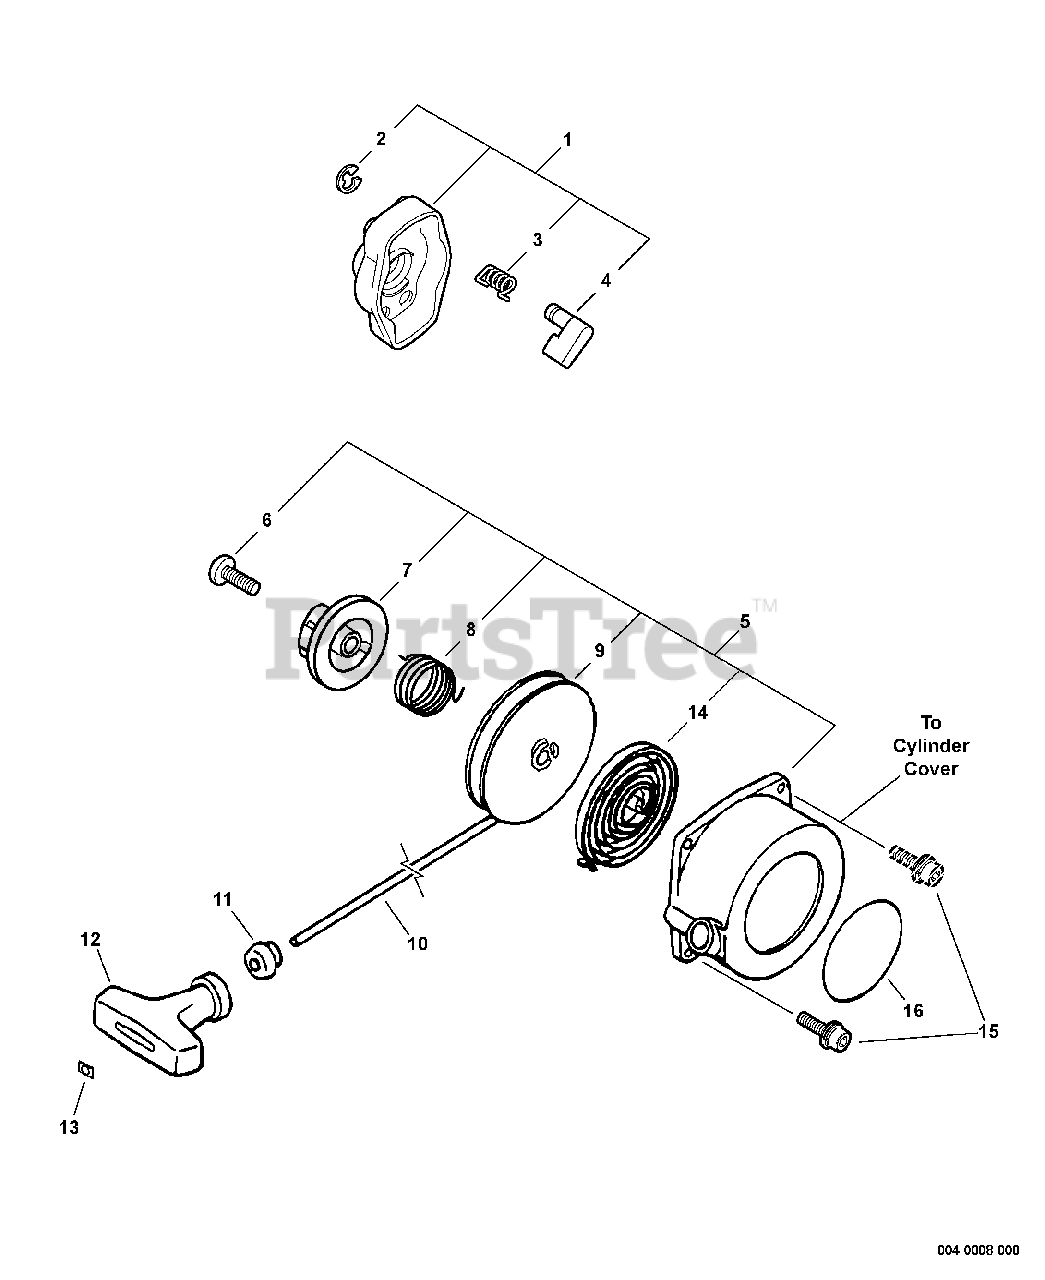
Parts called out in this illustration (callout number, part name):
1	PAWL ASSY, STARTER
2	E-RING 4
3	SPRING, RETURN
4	PAWL, STARTER
5	STARTER, RECOIL
6	SCREW
7	PLATE, CAM (NLA SEE PB 15-06)
8	SPRING, TORSION
9	REEL, ROPE
10	ROPE, STARTER 3×700
11	GUIDE, ROPE
12	GRIP, STARTER
13	RETAINER, ROPE
14	SPRING, RECOIL
15	BOLT 4×16
16	LABEL - ECHO -- I-30
